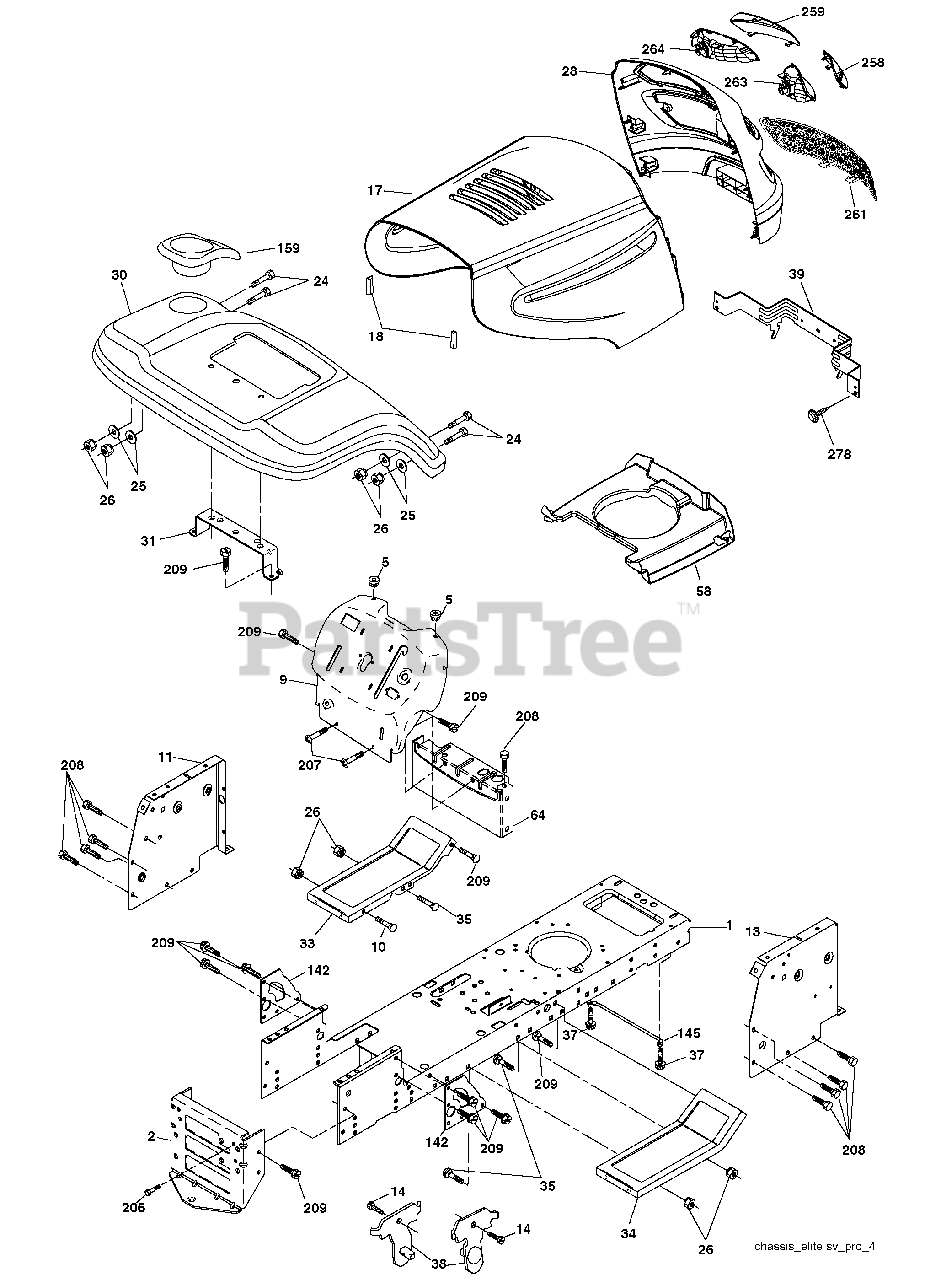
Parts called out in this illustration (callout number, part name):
1	Chassis
2	Drawbar
5	Bumper Hood/Dash
9	Dash P/L
10	Bolt Carriage 3/8-16 x 1
11	Panel Dash Lh
14	Screw Thdrol 3/8-16 x 1/2
17	Hood
18	Bumper Hood
24	Bolt Fin Hex 3/8-16 unc x 1 Gr. 5
25	Washer 13/32 x 13/16 x 12 Ga.
26	Nut Lock Hex W/Ins 3/8-16 unc
28	Grille/Lens Asm
30	Fender
31	Bracket Fender
33	Footrest LH
34	Footrest RH
35	Bolt RDHD SHT SQNK 3/8-16 x 3/4
37	Screw Thdrol 6/16-18 x 1/2 TYT
38	Bracket Asm Pivot Mower Rear
39	Bracket Pivot
58	Duct Air
64	Dash Lower STLT
142	Plate Reinforcement STLT
145	Rod Pivot Chassis/Hood
159	Cupholder
206	Bolt Shoulder 5/16-18
207	Screw Thdrol 5/16-18 x 1/2
208	Screw Thdrol 3/8-16 x 1/2
209	Screw Hexwsh Thdr 3/8-16 x 3/4
258	Lens Grille Pro RH
259	Lens Grille Pro LH
263	Bezel Grille RH
264	Bezel Grille LH
278	Screw 10 x 3/4 Single Lead Hex
278	Plug BTN BlK
278	Plug Dome Plastic
